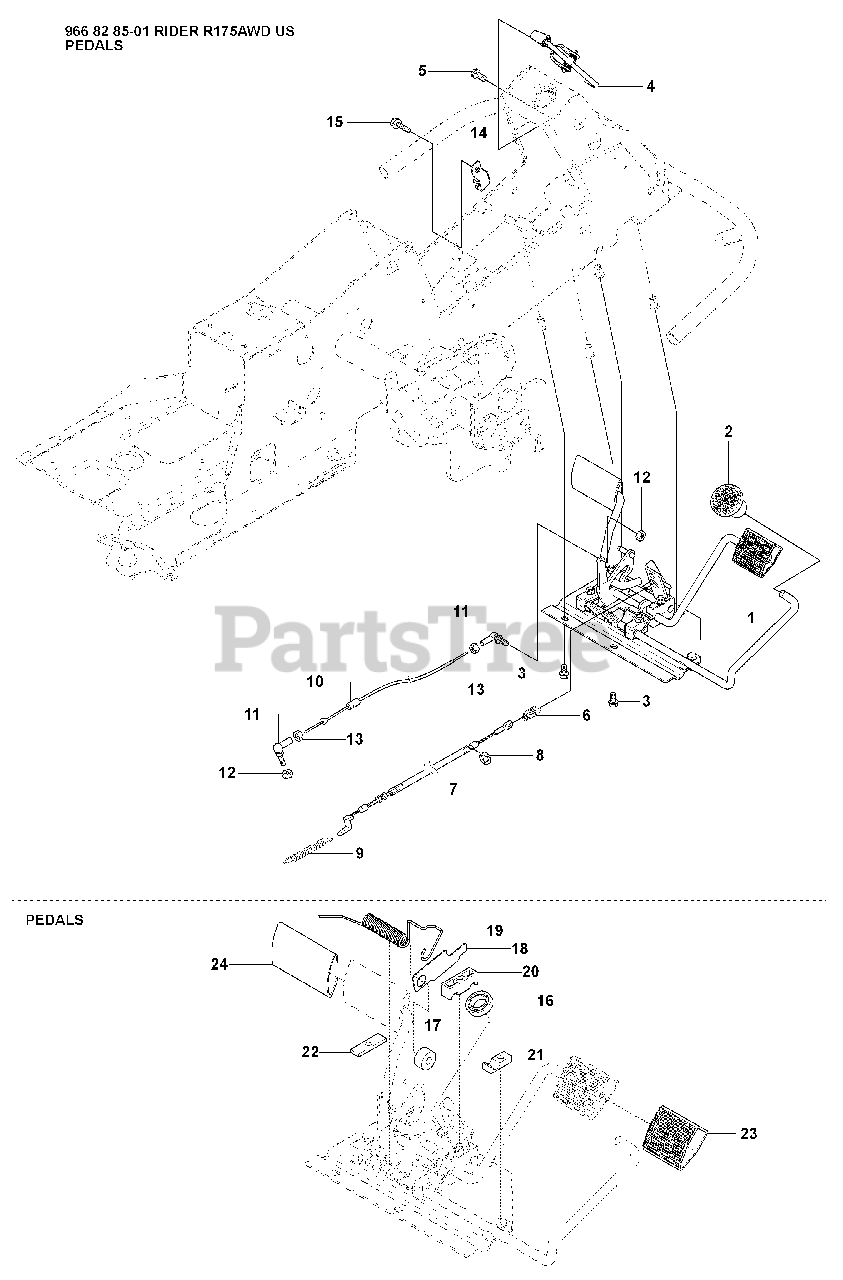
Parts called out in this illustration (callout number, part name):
1	PEDAL ASSEMBLY
2	KNOB
4	BRAKE LEVER ASSY
7	RP WIRE
10	%WIRE
11	CONNECTOR
12	LOCKNUT M5
14	BRACKET
16	BALL BEARING 6002-2RS1
17	ROLLER
18	PLATE
19	SPRING
20	PEDAL SHAFT CLAMP
21	SUPPORT
22	PLATE
23	PEDAL RUBBER
24	PEDAL RUBBER, SF
